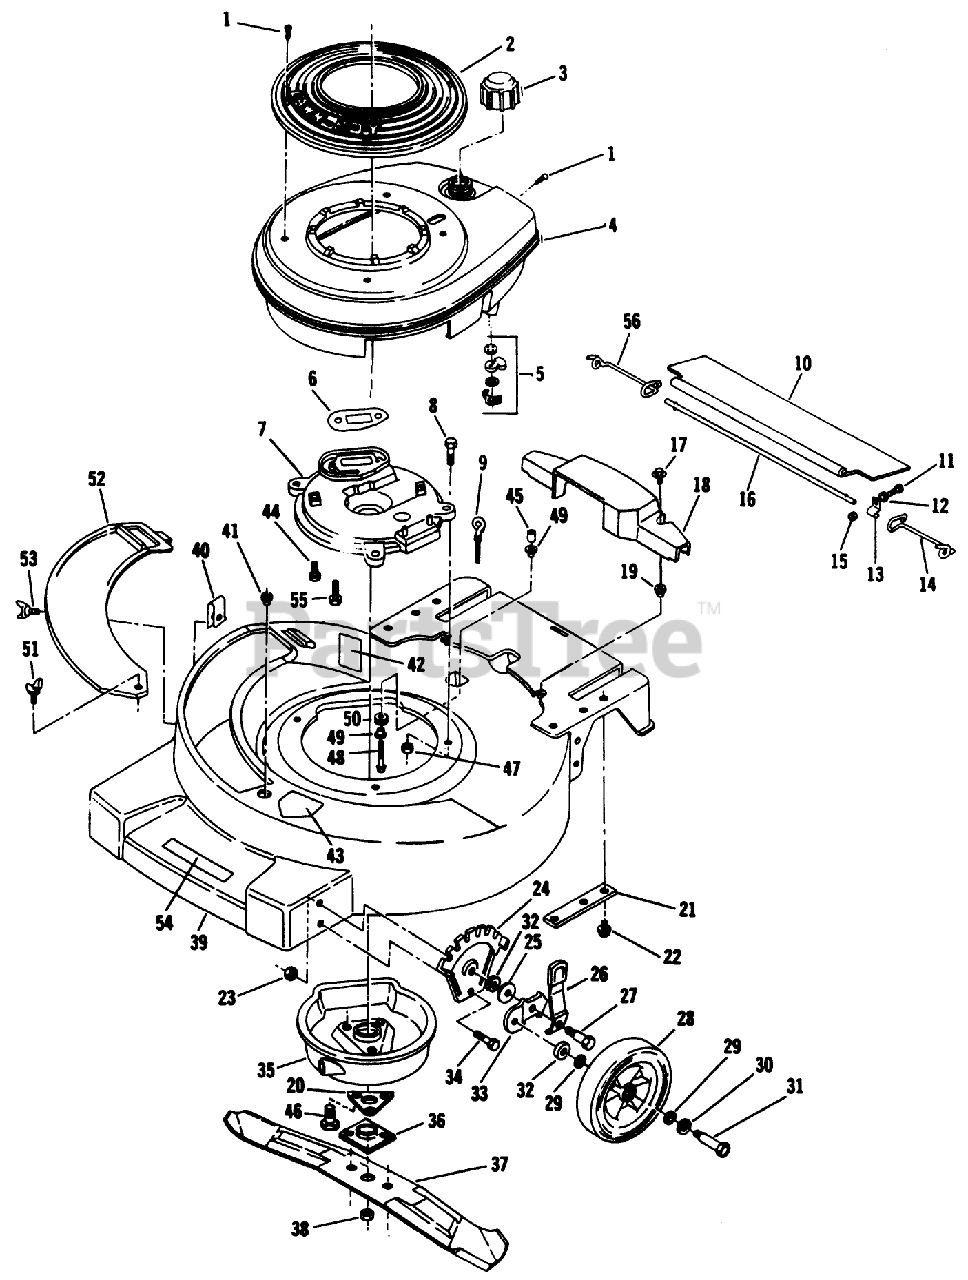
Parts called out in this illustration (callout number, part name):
1	SCREW - SELF TAPPING
3	FUEL CAP & INSERT
5	SHUT OFF VALVE KIT
7	PLATE,MUFFLER F
8	SCREW-HH
9	EYE BOLT WAS MFG
12	WASHER F
13	CLAMP ROD KMC
14	SPRIG T/SHLD ASOC
15	LOCKNUT E
16	ROD T/SHIELD ADV WIRE
17	SCREW SEMS TRM HEX HD
20	SUPPORT F
22	SCREW
23	LOCKNUT
25	WASHER
27	BOLT
29	WASHER
30	SPACER
31	BOLT WHEEL
32	WASHER WROUGHT
38	NUT-BLADE
45	SPACER
46	SCREW
47	NUT-LOCK F
49	SPACER ECK PRES
51	WING SCREW LAWRE
52	PLATE
55	SCREW V
56	SPRING;TRAILING SHIELD RH
